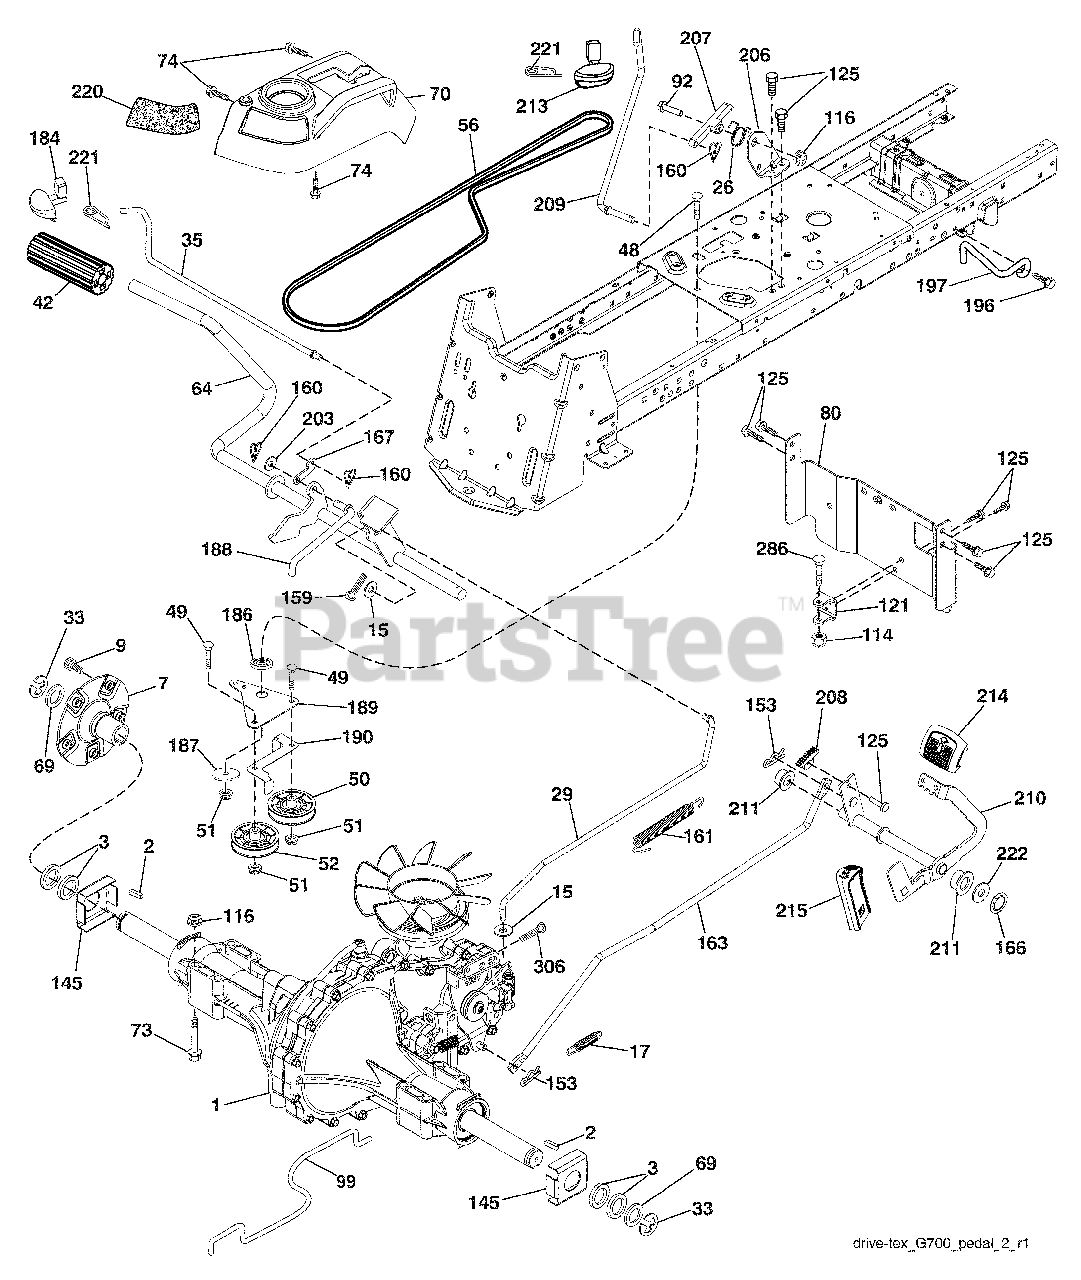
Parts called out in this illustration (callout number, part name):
2	Key 1/4 x 2.5
3	Washer Thrust Axle Hardened
7	Hub Asm. Wheel
9	Bolt Hub Wheel
15	Washer 13/32 x 13/16 x 16 Ga.
17	Spring, Brake
26	Spring Return Cruise
29	Rod, Brake
35	Rod, Brake, Park
42	Cover, Foot Pedal
48	Bolt Carr Sh 3/8-16 x 1-1/2 Gr. 5
50	Pulley Idler Flat
51	Lock Nut 3/8-16
52	Idler V-Groove 910" Offset
56	V-Belt, Drive
64	Shaft Asm. Pedal Brake Control
69	Washer 1-1/32 x 1-5/8 x 16 Ga.
70	Console Asm.
73	Bolt Hex 5/16-18 x 3 Gr. 5
74	Screw 1/4 x 1/2
80	Strap Torque
92	Bolt 5/16-18 x 1/2
99	Spring Bypass
114	Nut Lock Hex W/Ins. 5/16-18 unc
116	Nut Lock Hex Flange 5/16-18
121	Bracket Strap Torque
125	Screw 5/16-18 x 3/4
145	Washer Axle Flange
153	Retainer Spring
159	Pin Cotter 1/8 x 3/4
160	Retainer Clip
161	Spring, Return, Clutch
163	Rod Pedal Control
166	Nut Push .625
167	Latch Brake Parking
184	Handle Parking Brake
186	Spacer Retainer
187	Washer
188	Link Clutch Ground Drive
189	Bellcrank Ground Drive
190	Keeper Bellcrank Ground Drive
196	Screw 3/8-16 x 1
197	Bracket Clutch Anti-Rotation
203	Washer 11/32 x 11/16 x 16 Ga.
206	Bracket Mount Latch Cruise
207	Latch Control Cruise
208	Gear Sector Control Cruise
209	Rod Control Cruise
210	Rocker Asm. Pedal Control
211	Bearing Nylon
213	Knob Control Cruise
214	Pedal Forward
215	Pedal Reverse
220	Reflector RH
221	Retainer Spring Clip Handle
222	Washer 21/32 x 1-1/4 x 10 Ga.
286	Bolt 5/16-18 x 2.75
306	Pin Cotter 1/8 x 1
